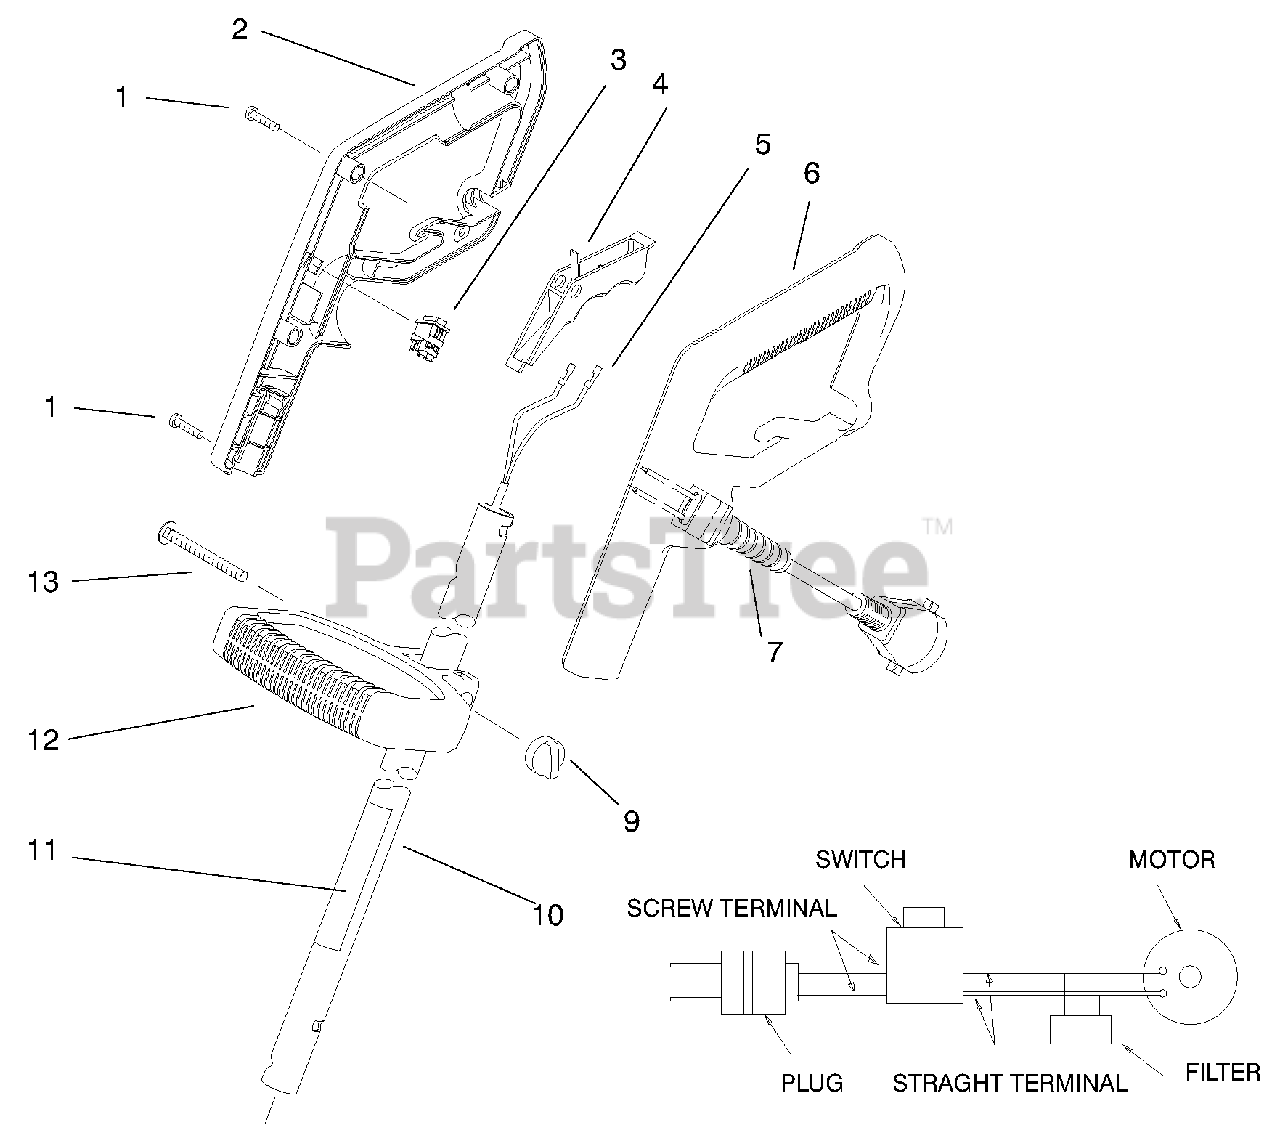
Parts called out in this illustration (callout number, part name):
1	SCREW-PPH
2	Grip-Hand R.H.
3	SWITCH - 230V
5	HARNESS - WIRE
6	Grip-Hand L.H.
7	CORD - POWER
9	KNOB, VFL/FFL
10	Tube Assembly (Incl. Ref. #11)
11	DECAL - WARNING
12	MID HANDLE
13	SCREW-CARR
